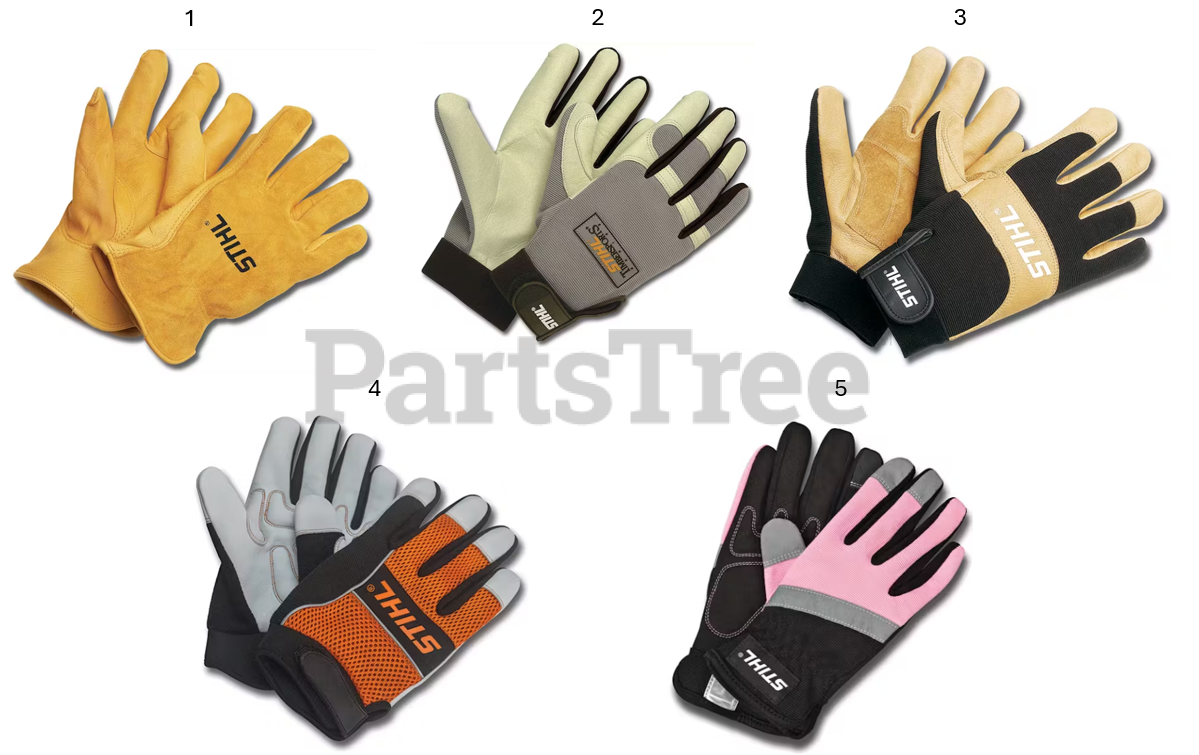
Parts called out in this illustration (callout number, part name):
1	Landscaper Glove L
2	Timbersport - L
3	Proscaper Glove L
3	Proscaper Glove XL
4	Meshback Gloves L
5	Cotton Candy Gloves M
